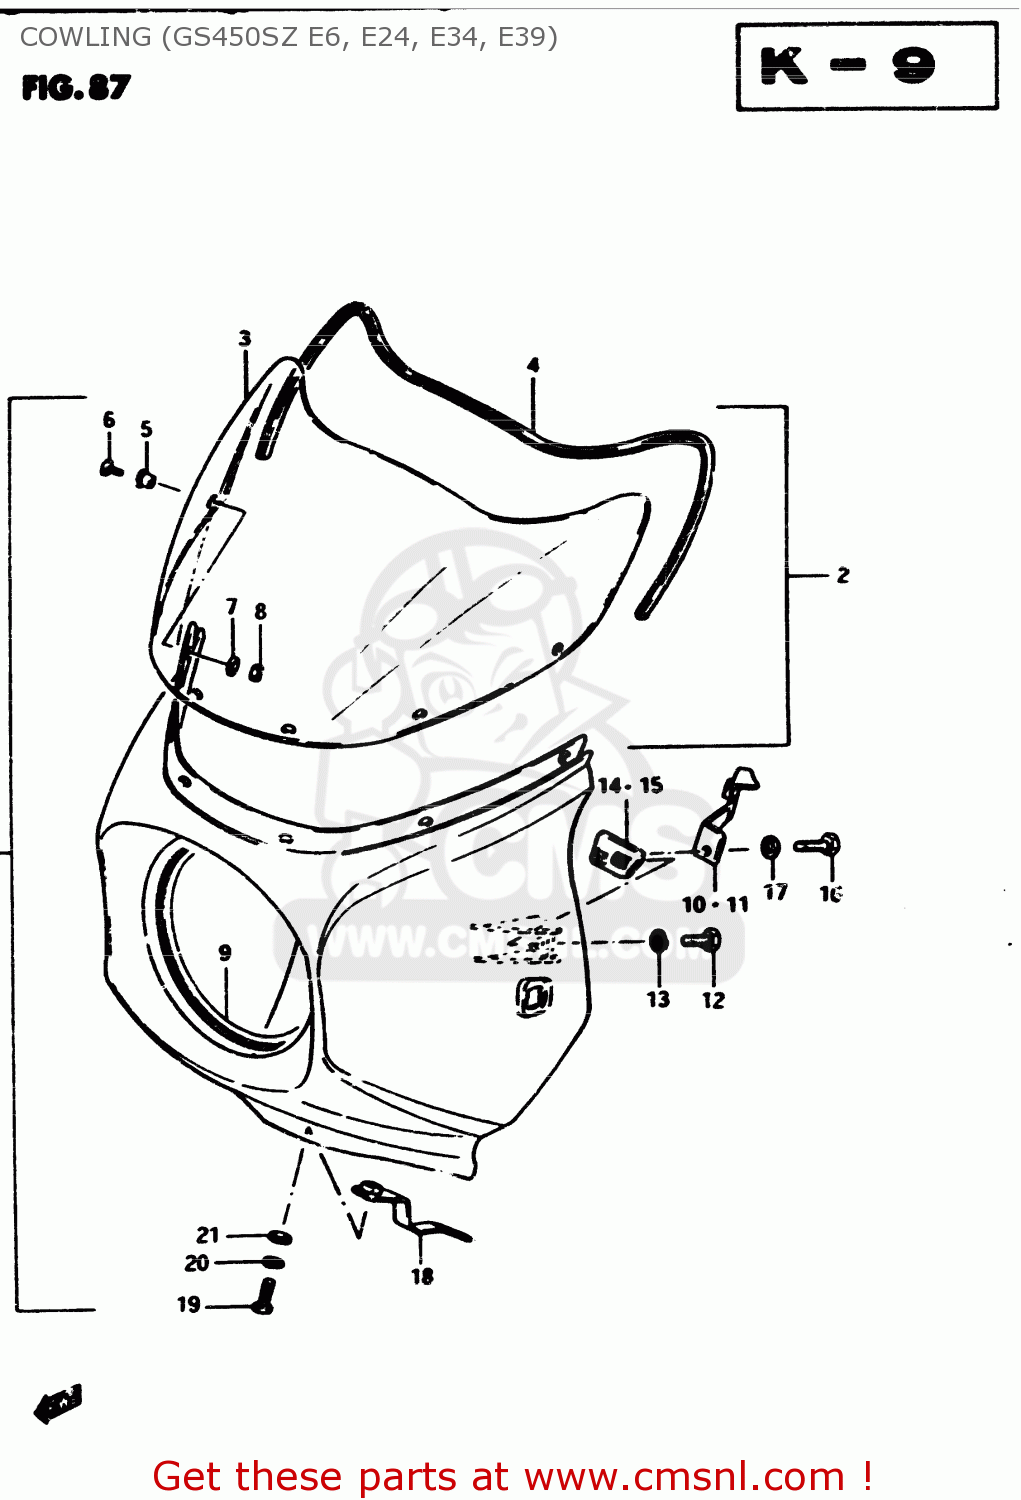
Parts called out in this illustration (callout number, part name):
1	COWLING ASSY (RED)
2	COWLING ASSY
3	WINDOW
4	MOULDING
5	CUSHION
6	SCREW
7	WASHER
8	NUT
9	MOLDING,HEADLAMP GRILL
10	BRACKET,COWLING RH
11	BRACKET,COWLING LH
12	BOLT
13	LOCK WASHER
14	BRACKET, FITTING RH
15	BRACKET, FITTING LH
16	BOLT, UPPER
17	WASHER (6.5X18X1.6)
18	BRACKET, LOWER
19	BOLT
20	LOCK WASHER
21	WASHER
